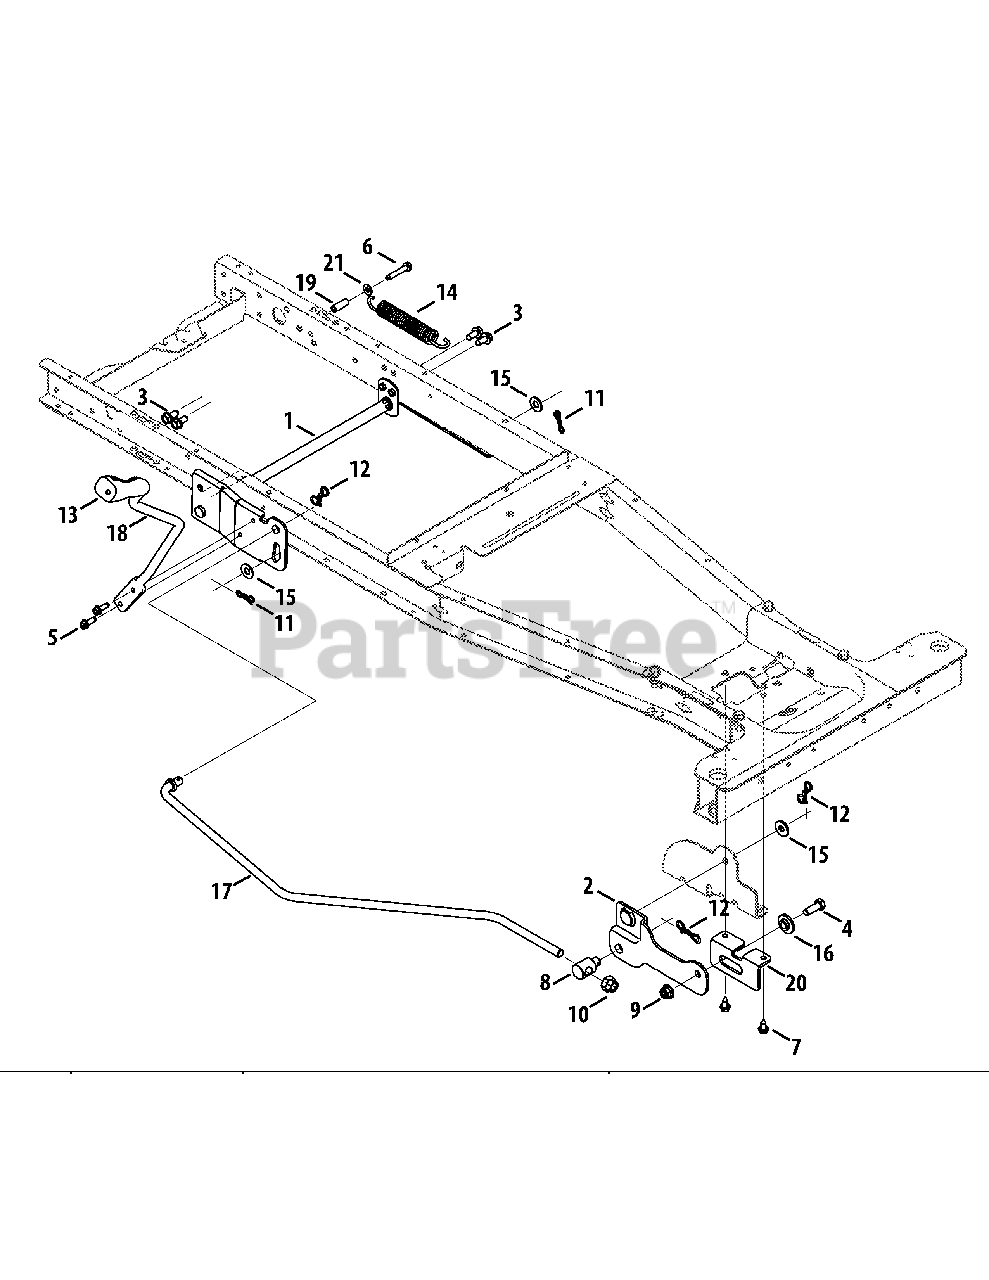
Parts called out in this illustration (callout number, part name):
1	Lift Assembly Shaft
2	Front Hanger Bracket Assembly
3	Tap Screw, 5/16-18 x .750
4	Hex Head Screw 3/8-16 x 1.00
5	Tap Screw 1/4-20, 0.750
6	Tap Screw 1/4-20, 1.50
7	Tap Screw 1/4-20 x .625
8	Ferrule .50 x50
9	Flange Lock Nut 3/8-16
10	Flex Lock Nut 1/2-13
11	Bow-Tie Cotter Pin
12	Bow-Tie Cotter Pin
13	Grip Handle 1/2
14	Extension Spring .85 OD x 5.915 Lg.
15	Flat Washer .406 x .875 x .059
16	Shoulder Spacer .625 ID x .169
17	Lift Link Rod
19	Spacer .260 x .375 x 1.030 Lg.
20	Front Deck Mounting Bracket
21	Flat Washer .250 x .630 x .052
